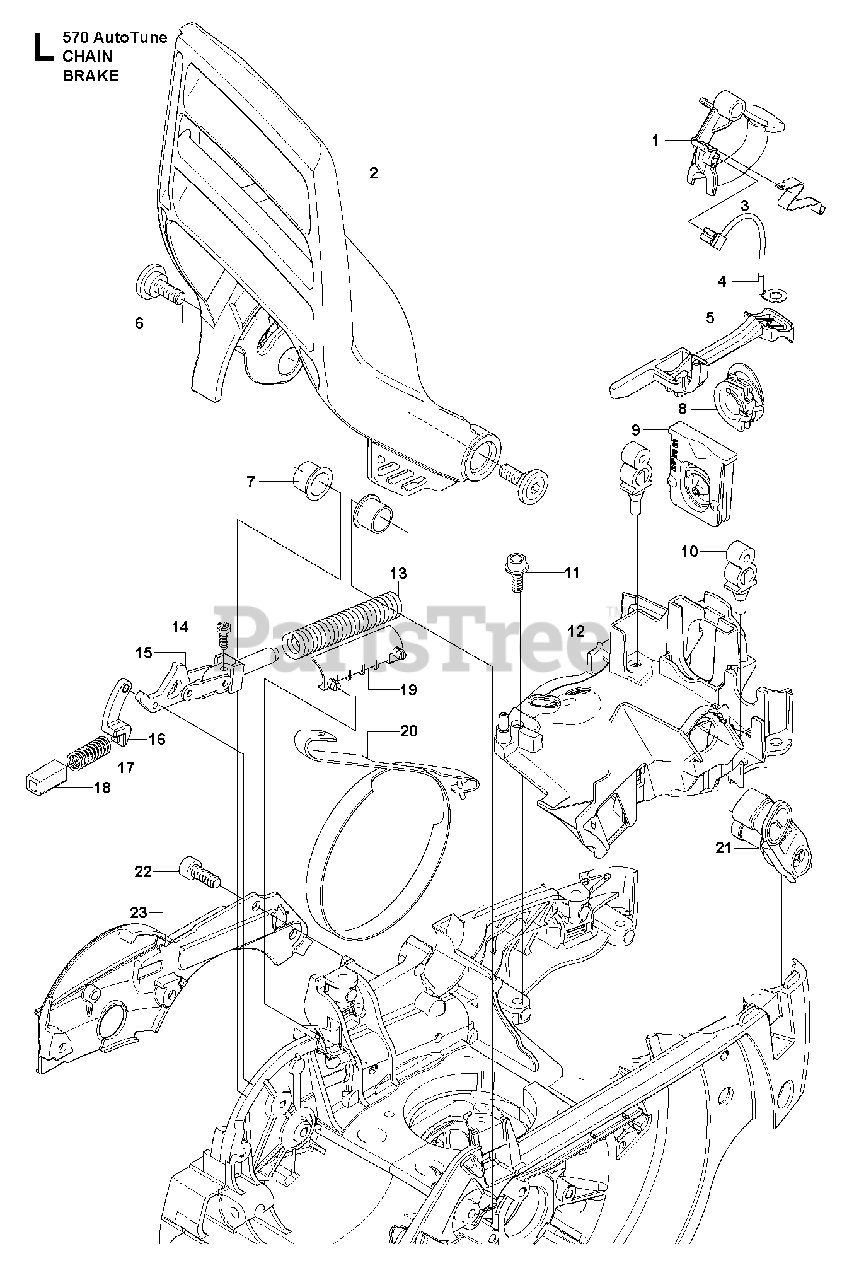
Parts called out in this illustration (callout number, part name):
2	CHAIN BRAKE
5	CHOKE CONTROL
13	BRAKE SPRING
15	KNEE JOINT
17	LOCK SPRING
19	%SUPPORT
20	BRAKE BAND
